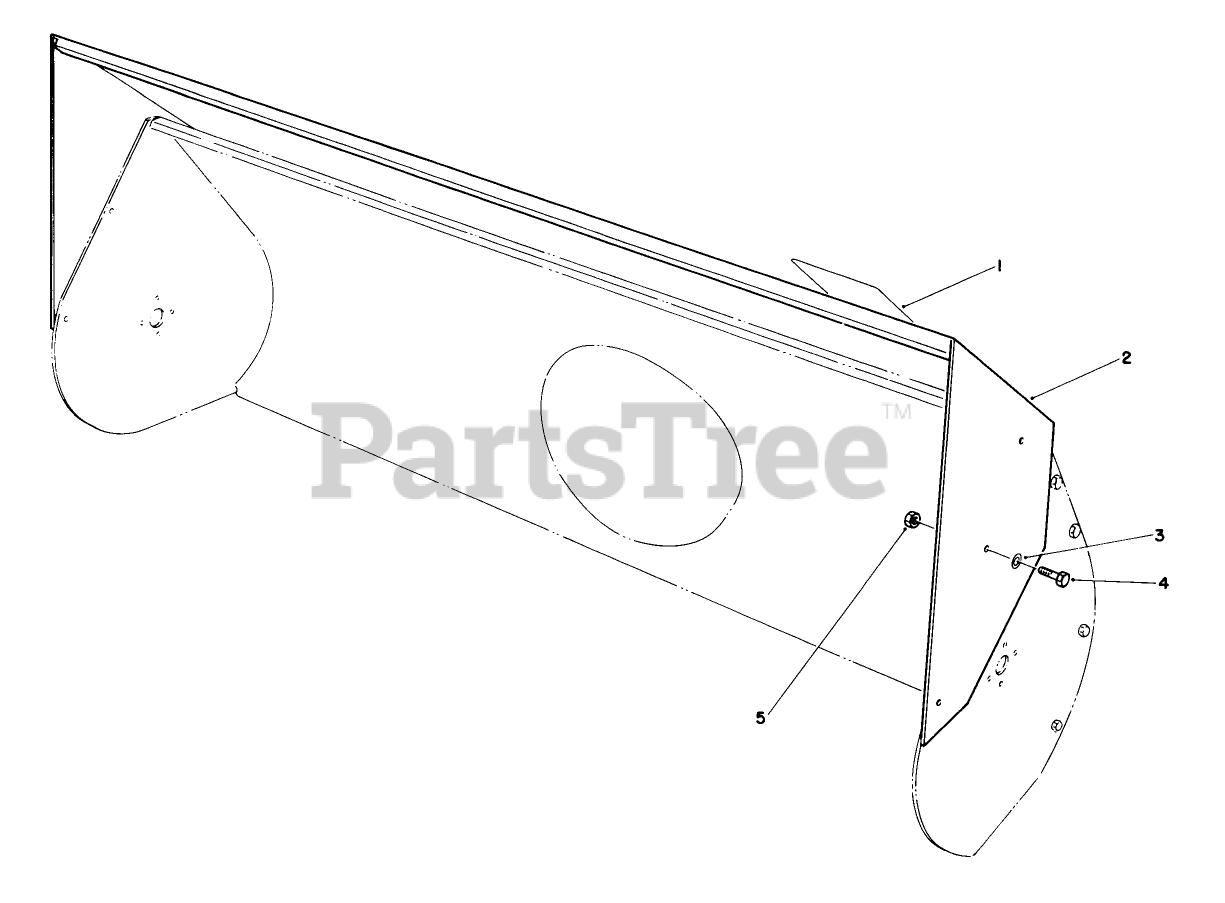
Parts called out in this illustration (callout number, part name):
1	Decal
2	Extension-Auger
3	WASHER-FLAT
4	SCREW-HH
5	NUT-LOCK, NI
